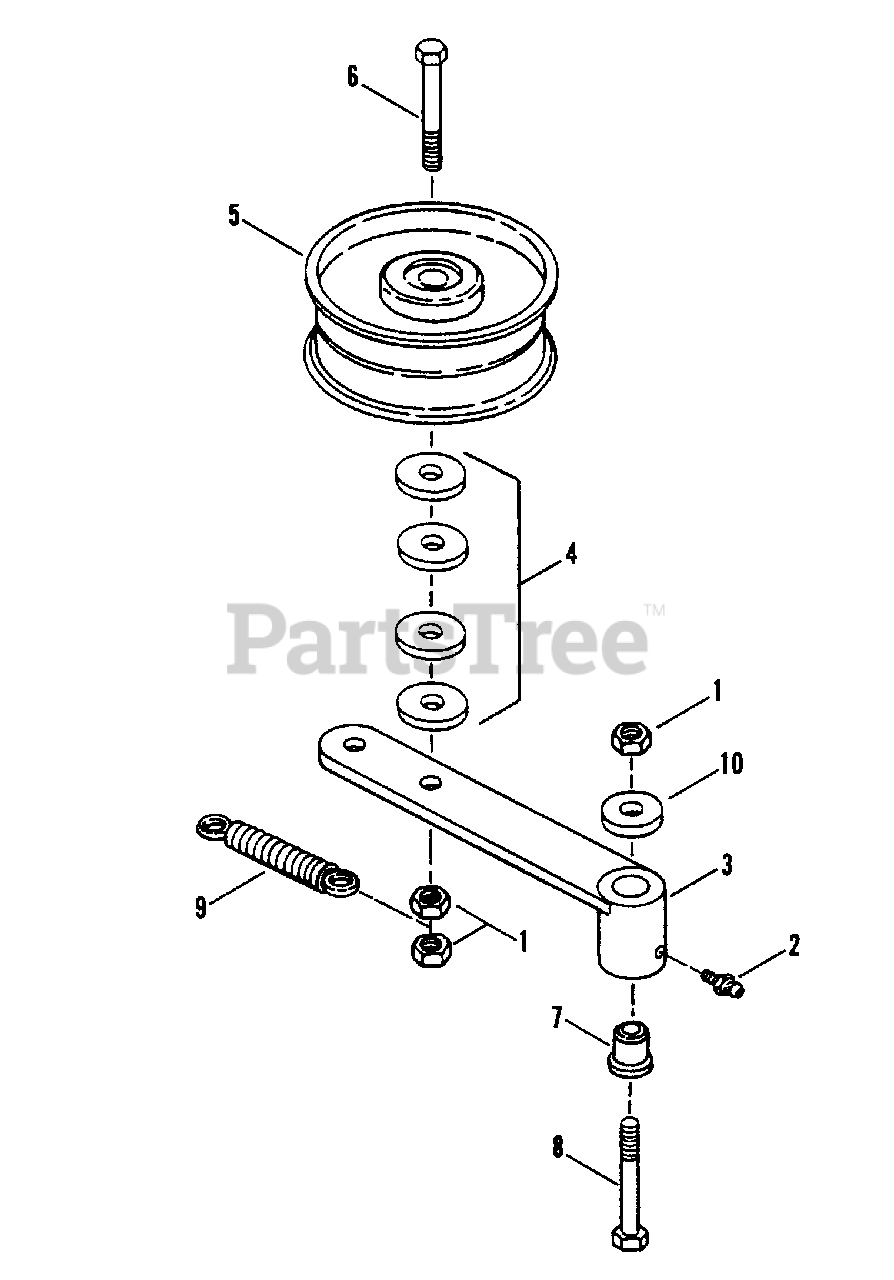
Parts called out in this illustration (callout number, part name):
1	NUT, 3/8-16 Nyloc
2	ZERK, 1/4-28
3	IDLER WELDMENT
4	WASHER, 3/8" Flat
5	PULLEY, Idler
6	SCREW, 3/8-16 x 2 1/2" Hex Head
7	SPACER, Pivot
8	SCREW, 3/8-16 x 3 1/4" Hex Head
9	SPRING, Idler Tension
10	BUSHING, 14 Gage Spacer
